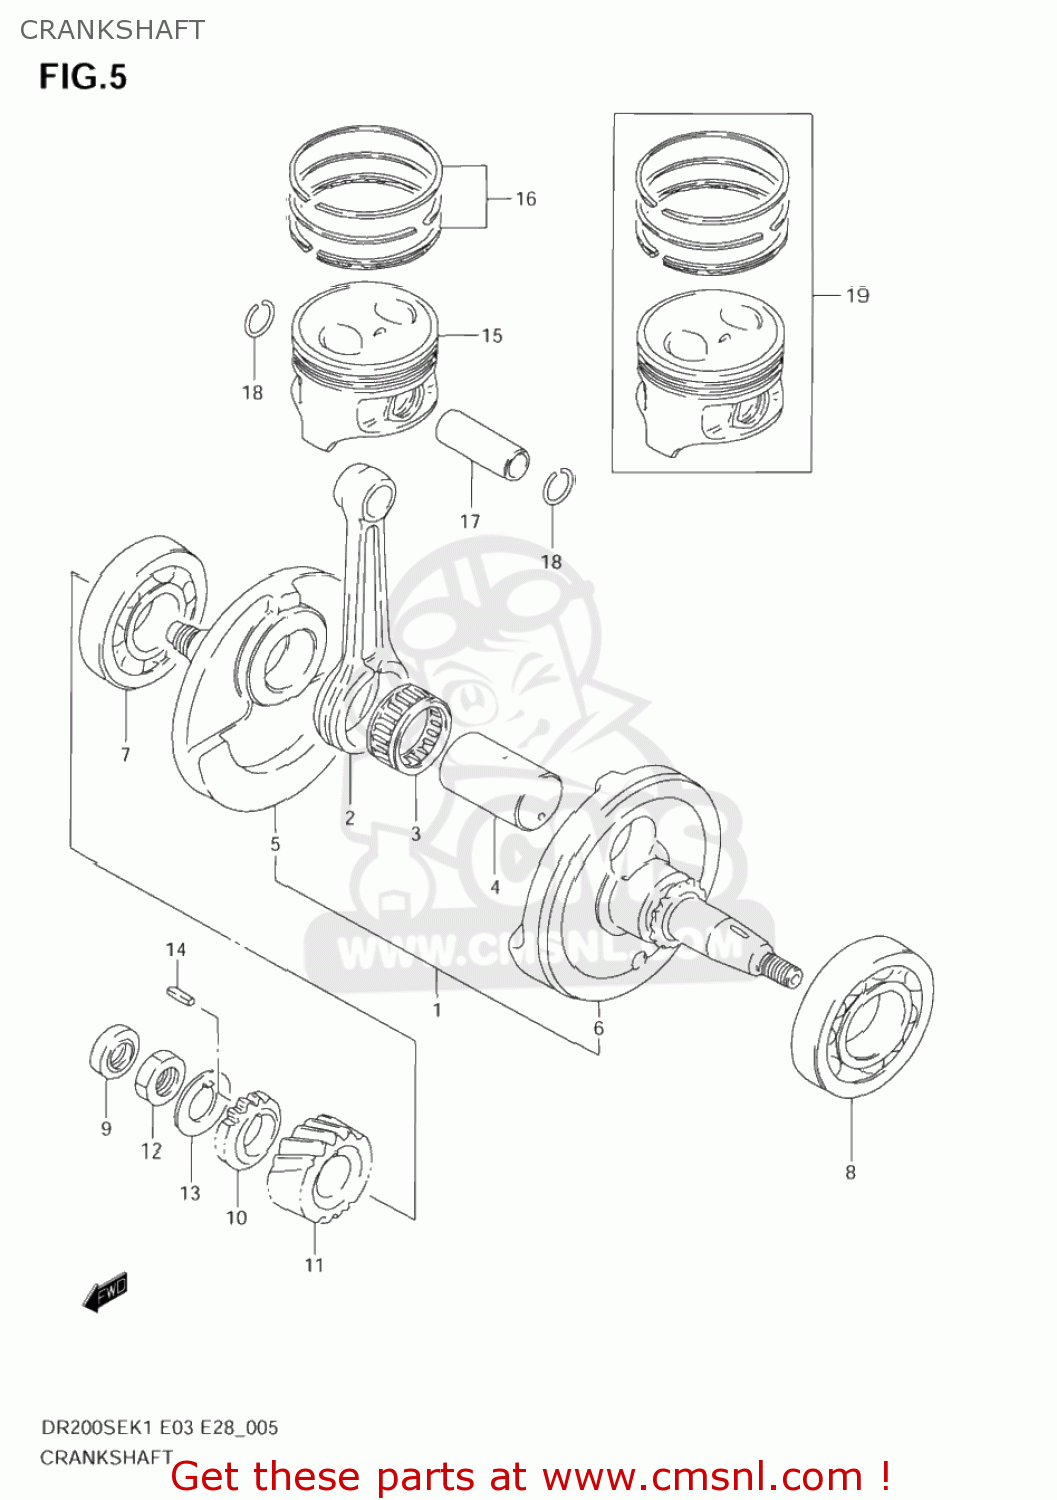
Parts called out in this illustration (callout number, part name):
1	CRANKSHAFT ASSY
2	CONNECTING ROD
3	BEARING(31X38X18)
4	PIN,CRANK
5	CRANKSHAFT,R
6	CRANKSHAFT,L
7	BEARING(28X68X18)
8	BEARING(35X72X17)
9	SEAL,OIL(12X21X7)
10	GEAR,OIL PUMP DRIVE(NT:15)
11	GEAR,PRIMARY DRIVE
12	NUT
13	WASHER
14	KEY
15	PISTON
16	RING SET,PISTON
17	PIN,PISTON
18	RING,SNAP 16MM
19	PISTON SET (OS:0.5)
